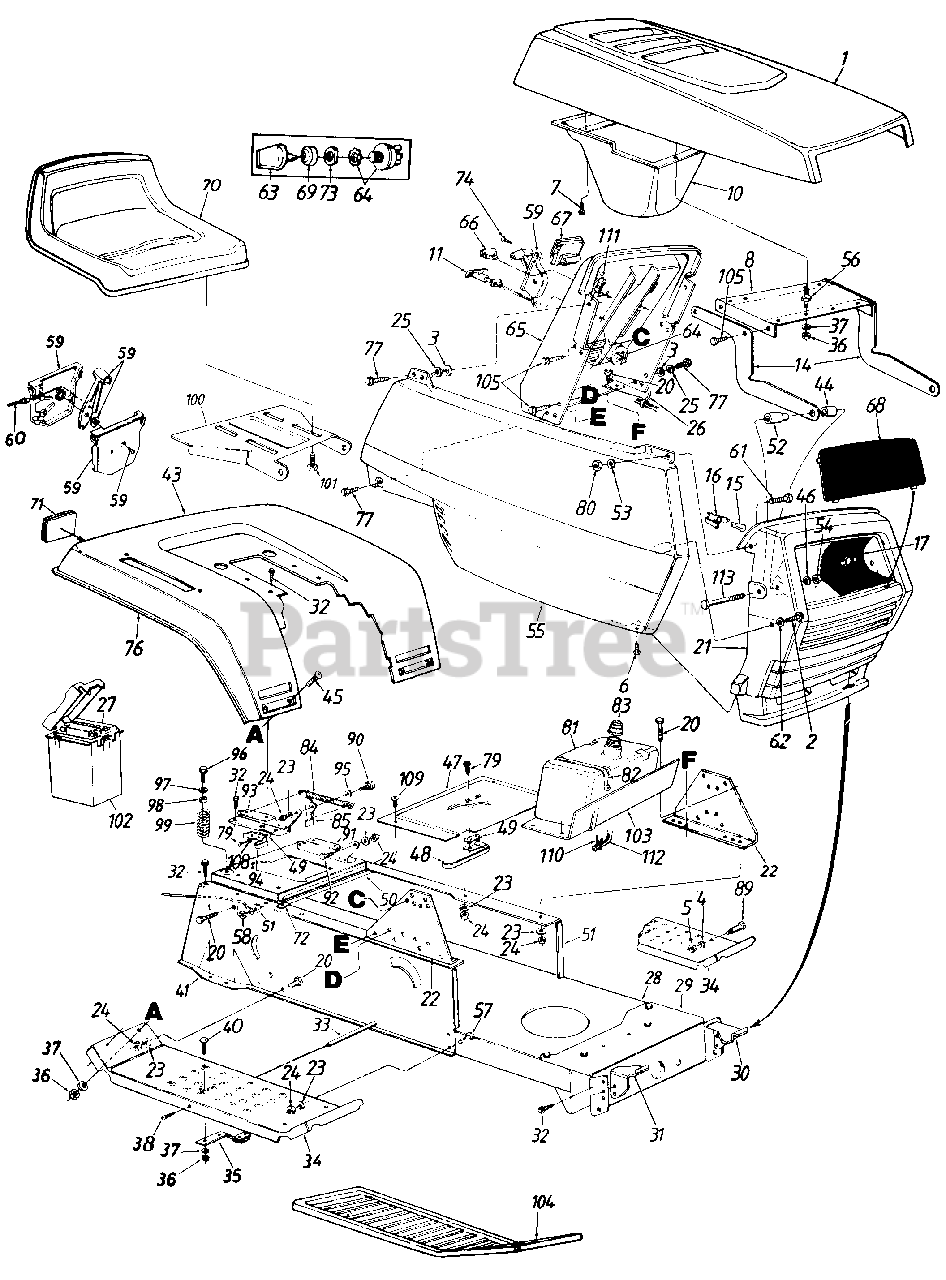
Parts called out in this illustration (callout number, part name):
3	Bolt Retainer 1/4" I.D.
4	L-Wash. 3/8" I.D.*
5	Hex Nut 3/8-16 Thd.*
6	Truss Mach. AB-Tap Scr. #10 x .5" Lg.
7	Hex Wash Hd. AB-Tap Scr. #8 x .5" Lg.
8	Hood Plate
11	Choke Control 29" Lg.
14	Hood Hinge
15	Lamp
16	Twist Lock-Lamp Socket
17	Reflector-Headlight
20	Hex Bolt 5/16-18 x .75" Lg.*
21	Grille
22	Dash Support Bracket
23	L-Wash. 5/16" I.D.*
24	Hex Nut 5/16-18 Thd.*
25	Fl-Wash. 1/4" I.D. x .93" O.D.
26	Cable Tie
27	12 Volt Battery
28	Lower Frame
29	Front Pivot Brk't.
30	Grille Mount Brk't.-L.H.
31	Grille Mount Brk't.-R.H.
32	Hex Wash. Hd. AB-Tap Scr. 5/16 x .75" Lg.
33	Running Board Rod
34	Running Board
35	Blade Brake Ass'y.
36	Hex Nut 1/4-20 Thd.*
37	L-Wash. 1/4" I.D.*
38	Truss Mach. Scr. 5/16-18 x .75" Lg.*
40	Carr. Bolt 1/4-20 x .62"
45	Carriage Bolt 1/4-20 x .50" Lg.*
46	Fl-Wash. .328" I.D. x .68" O.D.
47	Transmission Panel
48	Reverse Safety Switch
49	Insulator Nut Plate
50	Hitch Plate
53	Fl-Wash. .281" I.D. x .5" O.D.
54	Hex Cent. L-Nut 5/16-18 Thd.
55	Side Cover-R.H.
56	Double Ended Stud 1/4-20 Thd.
57	Truss Hd. Scr. 5/16-18 x 1.0" Lg.
58	Ext. L-Wash. 5/16" I.D.
59	Throttle Control Box Ass'y.
60	Throttle Control Wire 18.5" Lg.
61	Hex Bolt 1/4-20 x .62" Lg.*
62	Fl-Wash. .281" I.D. x .73" O.D.
64	Ignition Switch
66	Light Switch
67	Ammeter
68	Lens
69	Ignition Switch Cap
70	Seat Ass'y.
71	Reflector
72	Speed Nut #10Z
73	Ignition Switch Nut
74	Truss Mach. AB-Tap Scr. #10 x .5" Lg.
76	Trim Strip-81"
77	Hex Wash. Hd. Tap Scr. 1/4 x.75" Lg.
79	Hex Wash. Hd. AB-Tap Scr. #8 x .50" Lg.
80	Hex L-Nut 1/4-20 Thd.
81	Fuel Tank
82	Cable Tie
83	Fuel Cap Gauge
84	Ext. Spring 5.31" Lg.
85	Seat Lift Brkt.
89	Shoulder Bolt
90	Shld. Bolt .437" Dia. x .268"
91	Seat Pivot Brkt. Support-L.H.
92	Shld. Bolt .437" Dia. x .162"
93	Seat Pivot Brkt. Support-R.H.
94	Spring Switch
95	Spr.-Wash. .445" I.D.
96	Hex Wash. Hd. Tap Scr. 5/16-18 x 1 " Lg.
97	Fl-Wash. .344" I.D.
99	Compression Spring
100	Seat Pivot Bracket
101	Hex Tap Scr. 3/8-16 x .75"
102	Utility Box
103	Gasoline Tank Support
104	Foot Pad-L.H.
105	Hex Tap Scr. 1/4-20 x .5" Lg.
108	Fiber Washer
109	Truss Mach. Tap Scr. #10 x .5" Lg.
111	Speed Nut 1/4-20 Thd.
112	Fuel Line
113	Hex Bolt 5/16-18 x 2.75"
